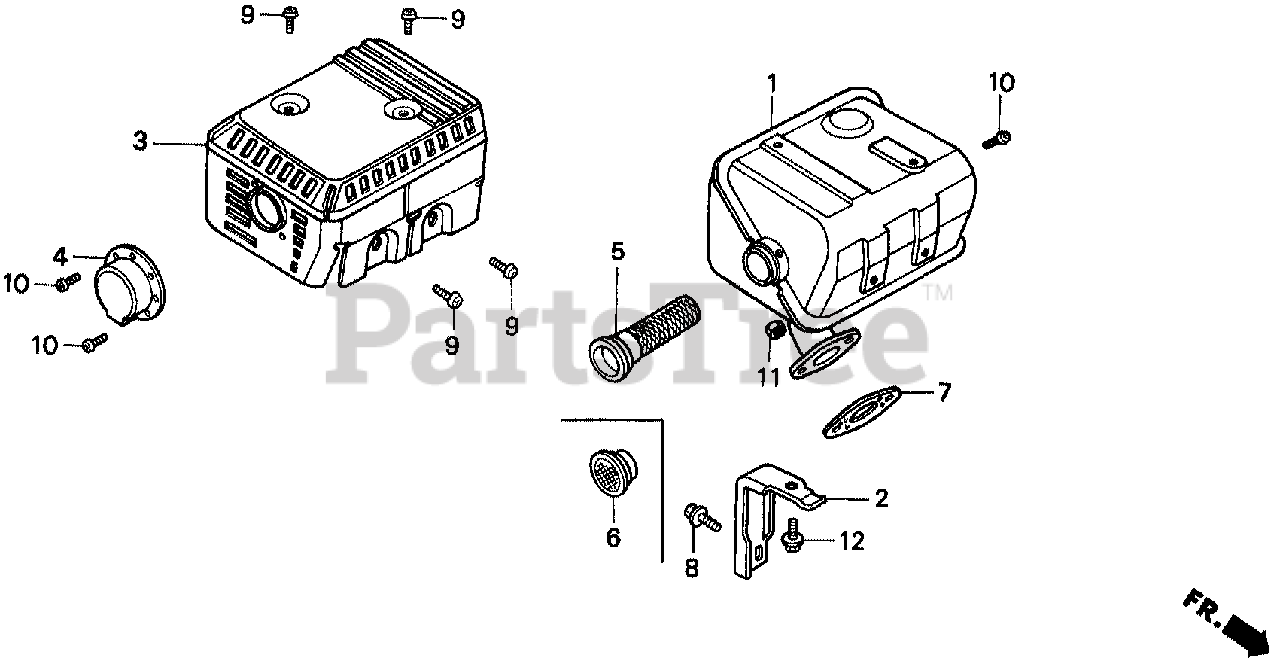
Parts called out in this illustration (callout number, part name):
1	MUFFLER (ARRESTER)
2	STAY, MUFFLER
3	PROTECTOR, MUFFLER
4	CAP, MUFFLER
5	ARRESTER, SPARK
7	GASKET, MUFFLER
8	BOLT, FLANGE (6X13)
9	SCREW, TAPPING (5X8)
10	SCREW, TAPPING (4X6)
11	NUT, HEX. (8MM)
12	BOLT, FLANGE (6X12)
